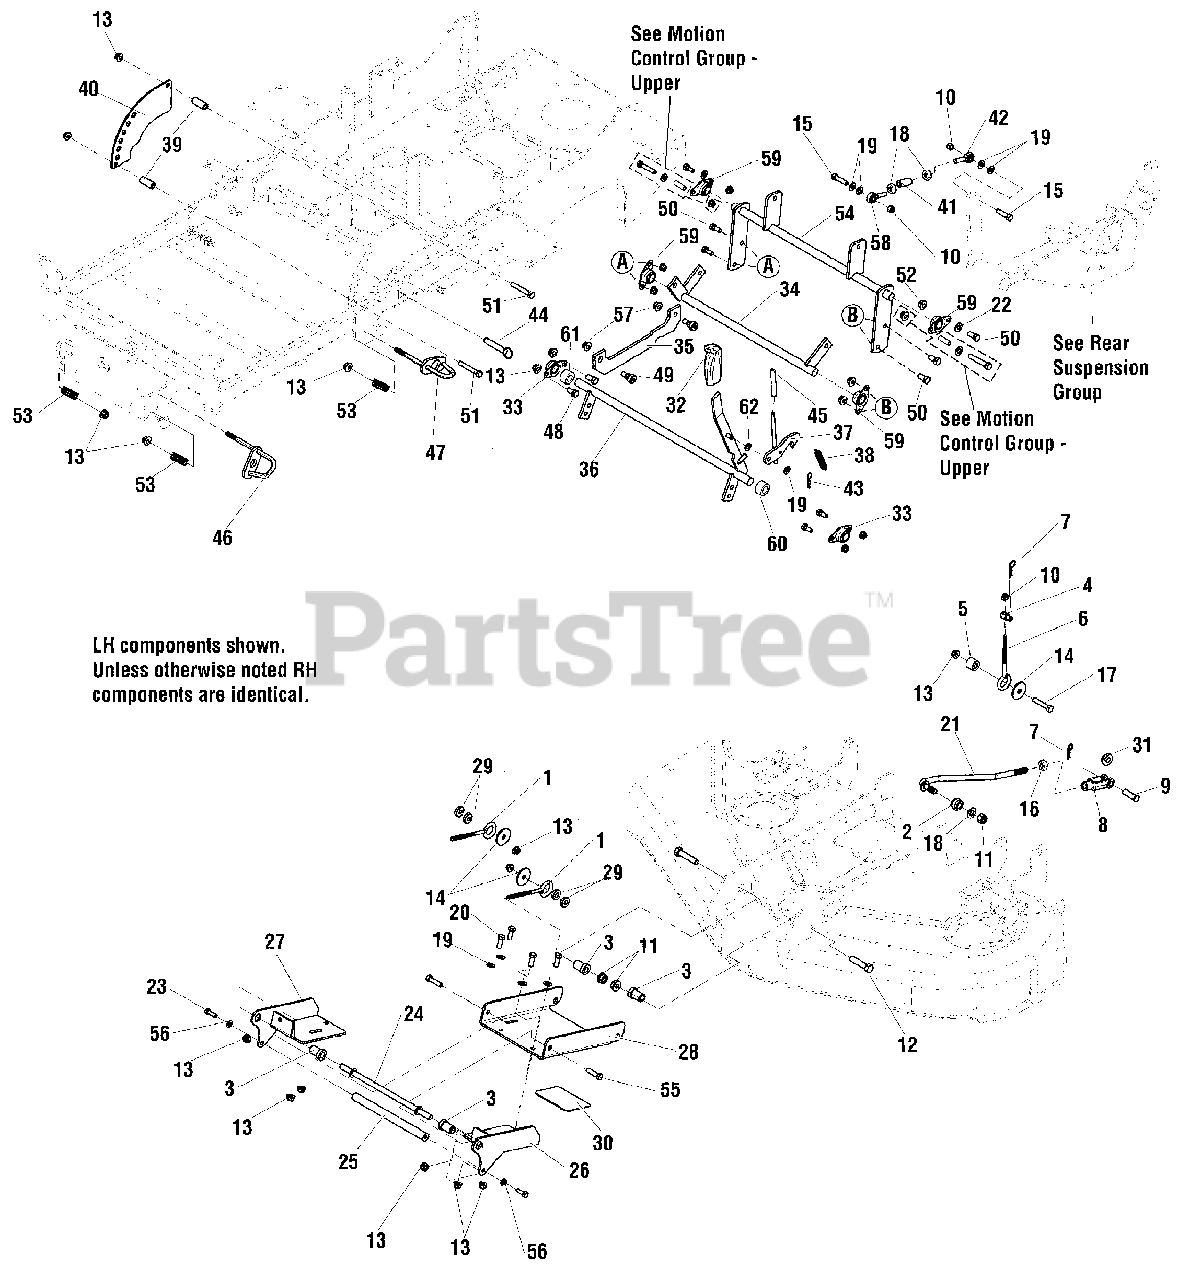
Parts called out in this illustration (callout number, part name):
1	EYE BOLT, 3/8-16 X 5, 2.88THRD, 1EYE, CZ
2	BUSHING, REAR QUICK TACH
3	SPACER, .53 X 1.00 X 1.00
4	ADJUSTER, BRAKE LINKAGE
5	SPACER, .39 X 1.00 X .88
6	EYE BOLT, 3/8-16 X 4-1/4, 1 EYE
7	PIN, HAIR, .0915 X 1-7/8
8	CLEVIS, 1/2-20, STEEL
9	PIN, CLEVIS, 1/2 X 1 1/2, YZP
10	NUT, 3/8-16 HEX NYLON LOCK
11	NUT, Hex, Nylon Lock, 1/2-20
12	BOLT, 1/2-20 X 2-1/4 GD5 CZ
13	NUT, 3/8-16 HEX NYLOCK FLANGE
14	WASHER, .41 X 1.75 X .14
15	BOLT, 3/8-16 X 1-1/2" GD5 CZ
16	NUT, 1/2-20 HEX JAM
17	BOLT, 3/8-16 X 1-3/4" GD5 CZ
18	NUT, 3/8-24 HEX JAM
19	WASHER, 3/8 SAE
20	BOLT, 3/8-16 X 1" GD5 CZ
21	ROD, DECK LIFT LINKAGE
22	WASHER, 5/16" SAE
23	BOLT, 5/16-18 X 1 GD5 YZ
24	SHAFT, HANGER
25	SHAFT, HANDLE, DECK MOUNT
26	WELD, DECK HANGER, LH
27	WELD, DECK HANGER, RH
28	PLATE, DECK HANGER SUPPORT
29	SPACER, .39 X 1.00 X .25
30	SAFETY WALK, 4.50 X 3.50
31	BUSHING, DECK SUPPORT
32	GRIP, BLACK FLEXIBLE
33	BEARING, BRONZE FLANGE, 3/4
34	WELD, DECK LIFT HANGER REAR - RED
35	LINK, DECK LIFT - RED
36	WELD, DECK HEIGHT SHAFT - RED
37	WELD, DECK LOCK
38	SPRING, EXTENSION
39	SPACER, .39 X .63 X 1.50
40	PLATE, DECK HEIGHT- INNER -RED
41	SLEEVE, .32 X .63 X 1.50, TAPPED 3/8-24
42	BALL JOINT, 3/8-24 MALE
43	PIN, COTTER, 1/8 X 3/4
44	HITCH PIN ASSEMBLY, 1/2" X 2.50"
45	COVER, VINYL HANDLE
46	WELD, QUICK RELEASE HANDLE - RED
47	WELD, QUICK RELEASE HANDLE, REAR - RED
48	BOLT, 3/8-16 X 3/4" GD5 CZ
49	BOLT, 3/8-16 X 3/8, 1/2 SHOULDER
50	BOLT, 5/16-18 X 3/4 GD5
51	BOLT, 3/8-16 X 2-1/4" GD5 CZ
52	NUT, 5/16-18 HEX NYLOCK FLANGE
53	SPRING, COMPRESSION
54	WELD, COMPENSATOR ASSM. - RED
55	BOLT, 3/8-16 X 1-1/4" GD5 CZ
56	WASHER, 5/16 LOCK YZ
57	NUT, 3/8-16 HEX SERRATED FLANGE
58	BALL JOINT
59	BEARING, BRONZE FLANGE, 3/4"
60	SPACER, .76 X 1.00 X .50
61	SPACER, .76 X 1.00 X 1.00
62	WASHER, WAVE, M10
